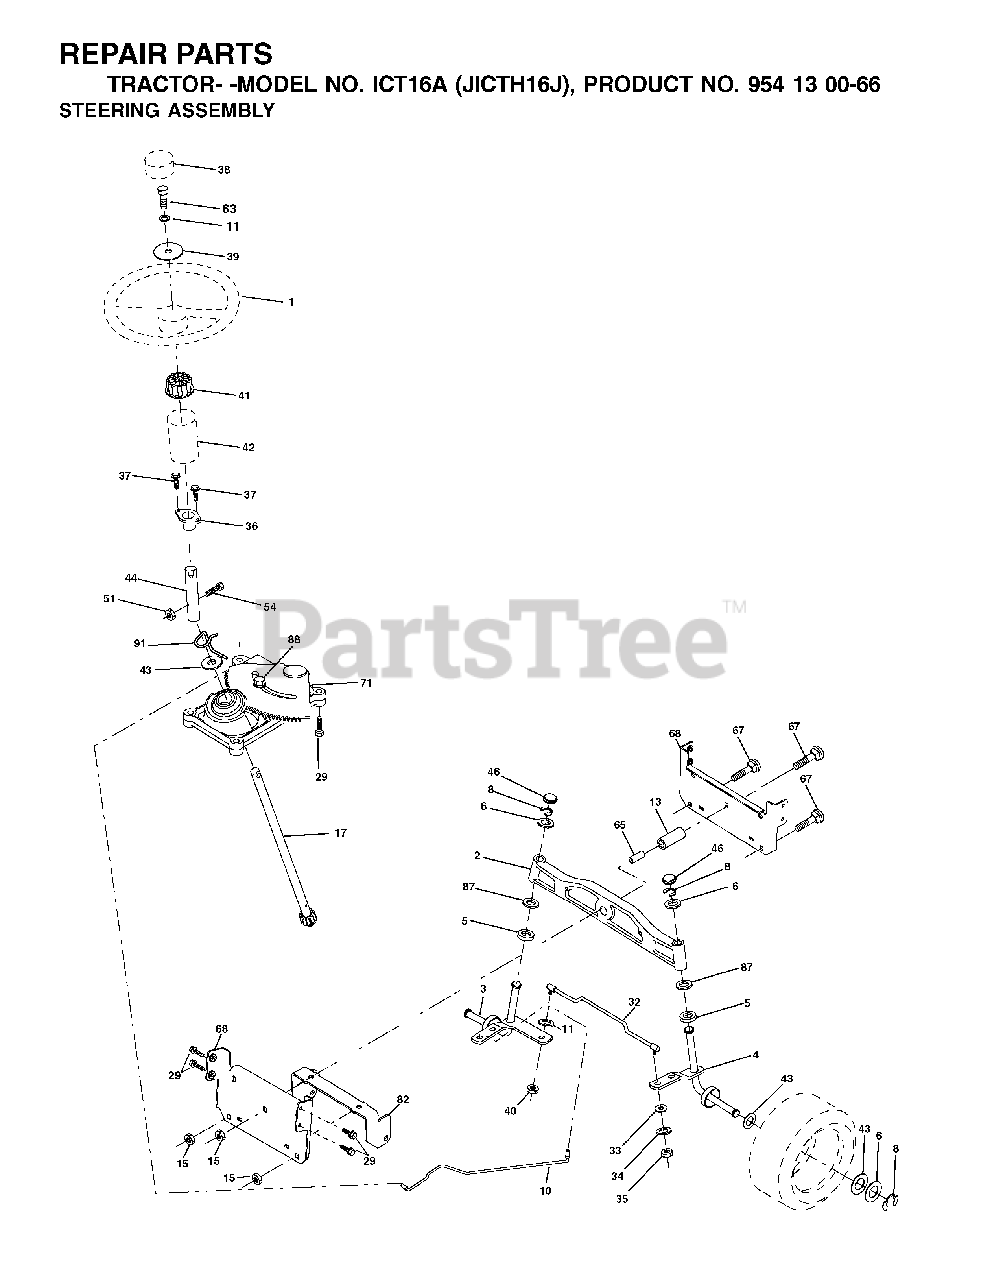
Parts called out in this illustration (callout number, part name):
2	AXLE ASM
3	SPINDLE.ASM.LH.15"TIRES
4	SPINDLE.ASM.RH.15"TIRES
8	RING CLIP
10	DRAGLINK.15".TIRES.2001
11	WASHER, LOCK 3/8
13	TUBE, PIVOT AXLE
15	NUT
17	SHAFT ASM
29	SCREW 3/8-16X3/4
32	ROD.ASM.TIE.BALL.JOINT.NOVAN
33	WASHER M
34	LOCKWASHER
35	NUT, CROWNLOCK
36	BUSHING, STEERING
39	WASHER 13/32 X 2-3/8 X 12 GA
40	GRIPCO NUT
41	STEERING WHEEL ADAPTOR
42	BOOT.STEERING.SHAFT.BLACK
44	EXT SHAFT STEERING
46	CAP.SPINDLE
51	NUT.71038.31-18.HEX.NYLOCK
54	BOLT.5/16-18X1-1/4 FULL.THREAD
65	SPACER BRACE AXLE
67	BOLT
68	BRACE.AXLE.15"TIRES
71	STEERING ASM
82	BRACKET
87	WASHER, FLAT .781 X 1 1/2"
88	BOLT, SHOULDER 7/16-20
91	CLIP.STEERING
